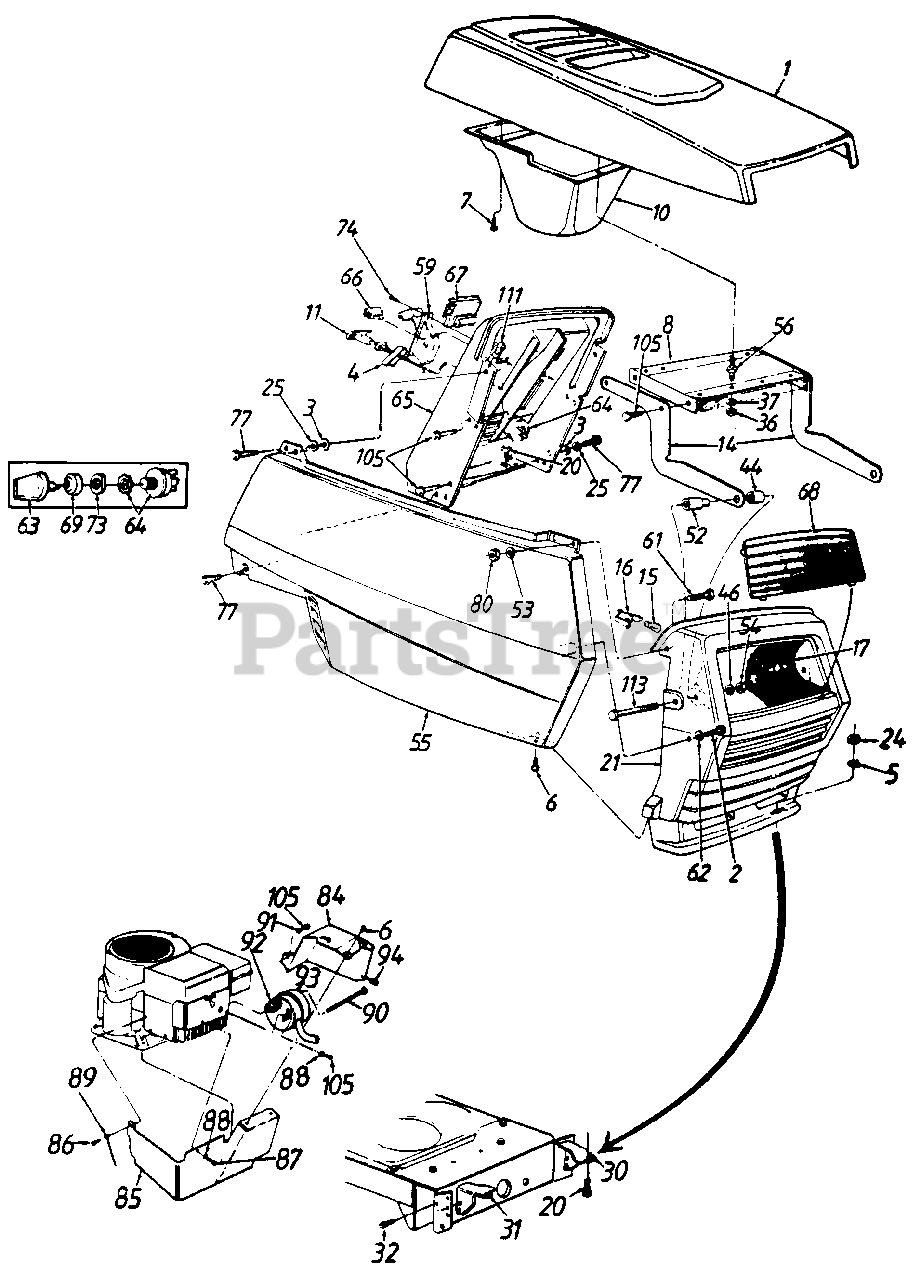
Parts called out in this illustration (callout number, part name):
3	Bolt Retainer 1/4" I.D.
4	Retainer Clip
5	Fl-Wash. .34" I.D. x .68"
6	Truss Mach. AB-Tap Scr. #10 x .5" Lg.
7	Hex Wash Hd. AB-Tap Scr.#8 x .5" Lg.
8	Hood Plate
11	Choke Control 29" Lg.
14	Hood Hinge
15	Lamp
16	Twist Lock\-Lamp Socket
17	Reflector\-Headlight
20	Hex Bolt 5/16-18 x .75" Lg.*
21	Grille
24	Hex Nut 5/16-18 Thd.*
25	Fl-Wash. 1/4" I.D. x .93" O.D.
30	Grille Mount Brk't.\-L.H.
31	Grille Mount Brk't.\-R.H.
32	Hex Wash. Hd. AB-Tap Scr. \0\05/16 x .75" Lg.
36	Hex Nut 1/4-20 Thd.*
37	Bell-Wash. .265" I.D. x. .75"
44	Spacer .33" I.D. x .625" O.D.
46	Fl-Wash. .328" I.D. x .68" O.D.
52	Shld. Spacer .33" I.D.
53	Fl-Wash. .281" I.D. x .5" O.D.
55	Side Cover -R.H.
56	Double Ended Stud 1/4-20 Thd.
59	Throttle Control Box Ass'y.
61	Hex Bolt 1/4-20 X .62 " Lg.*
62	Fl-Wash. .281" I.D. x .73" O.D.
64	Ignition Switch
65	Dash Panel
66	Light Switch
67	Ammeter
68	Lens
69	Ignition Switch Cap
73	Igntion Switch Nut
74	Truss Mach. AB-Tap Scr.#10 x .5" Lg.
77	Hex Wash. Hd. Tap Scr. 1/4 X .75" Lg.
80	Hex L-Nut 1/4-20 Thd.
84	Muffler Head Shield\-L.H.
85	Muffler Head Shield\-Front
86	Truss Mach. Scr. 5/16-18 X .75" Lg.
87	Hex Bolt 1/4-20 x 3/8" Lg.
88	Spr. Wash. .265" I.D. x .562"
89	Engine Ground Wire
90	Shld. Bolt 7/16" Dia. x 3-5/8" Lg.
91	L-Wash. 1/4" I.D.*
92	Gasket
93	Muffler
94	Speed Nut #10-24 Thd.
105	Hex Tap Scr. 1/4-20 X .5" Lg.
111	Speed Nut 1/4-20 Thd.
113	Hex Bolt 5/16-18 x 2.75"
